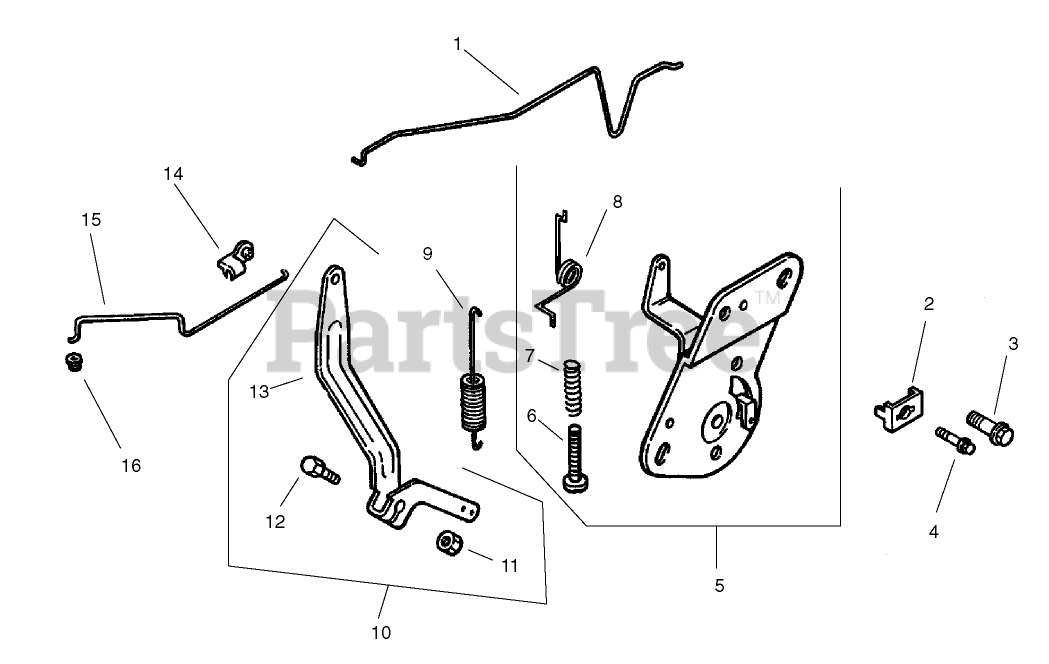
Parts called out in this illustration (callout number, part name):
1	Linkage-Choke
2	CLAMP-CABLE
3	SCREW-FLANGE, THREAD FORMING (M5X0.8X16)
4	Screw-Socket, 6 Lobed (Thread Forming, M6x1.0x20)
5	Control, speed assembly (Includes 6-8)
6	Screw-SPH,M4x0.7x25
7	Spring-Control, Speed
8	Spring-Return, Choke
9	Spring-Governor
10	Kit, Governor Lever (Incl 10-12)
11	Nut-Flange, Hex (1/4-20)
12	Bolt-Square Neck, Round Head (1/4-20x1)
13	Lever-Governor
14	BUSHING-RETAINING, LINKAGE
15	Linkage-Throttle
16	BUSHING-LINKAGE, THROTTLE
